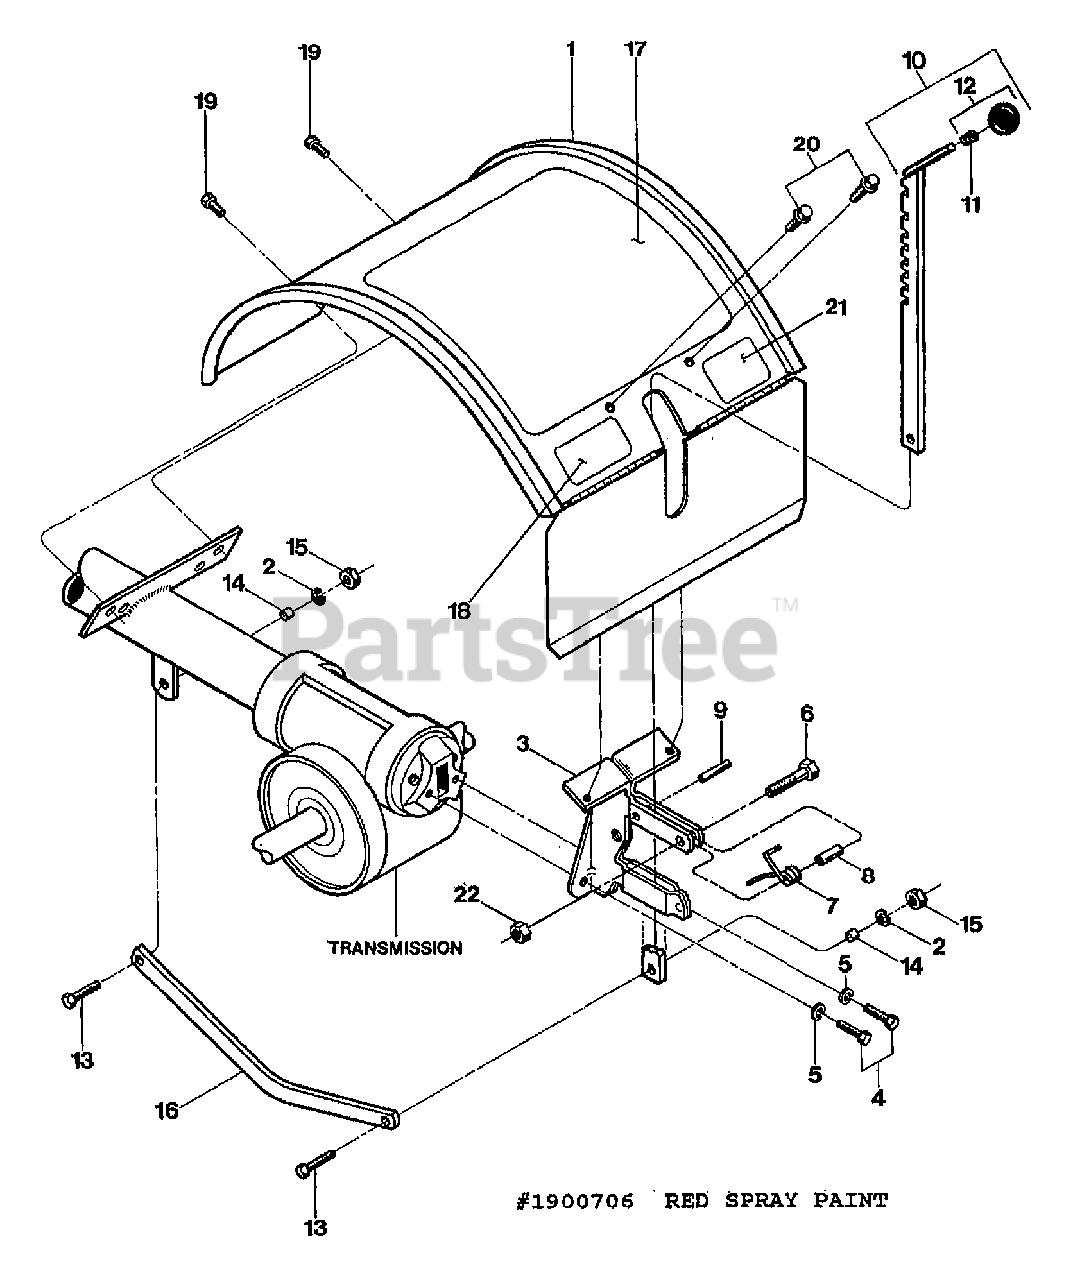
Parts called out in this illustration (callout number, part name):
1	HOOD W/DECALS PONY OPC
2	WASHER-LK .375 @ DEPL
3	BRKT W/ROLL PIN (9308)
4	SCR-HHC 5/16-18X.75 GR 5 ZP (BRACKET TO REAR BEARING CAP)
5	WASHER-LK .312 ZP
6	SCR-HH 1/4-20X1.0
7	SPRING-TORSION
8	SPACER-.250X.343X.375
9	PIN-ROLL .25 X 1
10	DEPTH REGULATOR W/KNOB (INCL. 11-12)
11	RING-TOLERANCE .5325 ID
12	KNOB-CONTROL
13	SCR-HH 3/8-16X1.25
14	BUSHING-.5X.375X.3
15	NUT-HEX 3/8-16 ZP
16	DRAG BAR-BENT
17	DECAL-HOOD OPER INST OPC
18	DECAL-HOOD LOGO PONY OPC
19	SCR-HWH 5/16-18 X .5 STH
20	SCR-HWH 1/4-20 X .5 STH (ATTACHES HOOD TO DEPTH REGULATOR BRACKET)
21	DECAL-TINE WARN SM FRAME
22	NUT-LK 1/4-20
